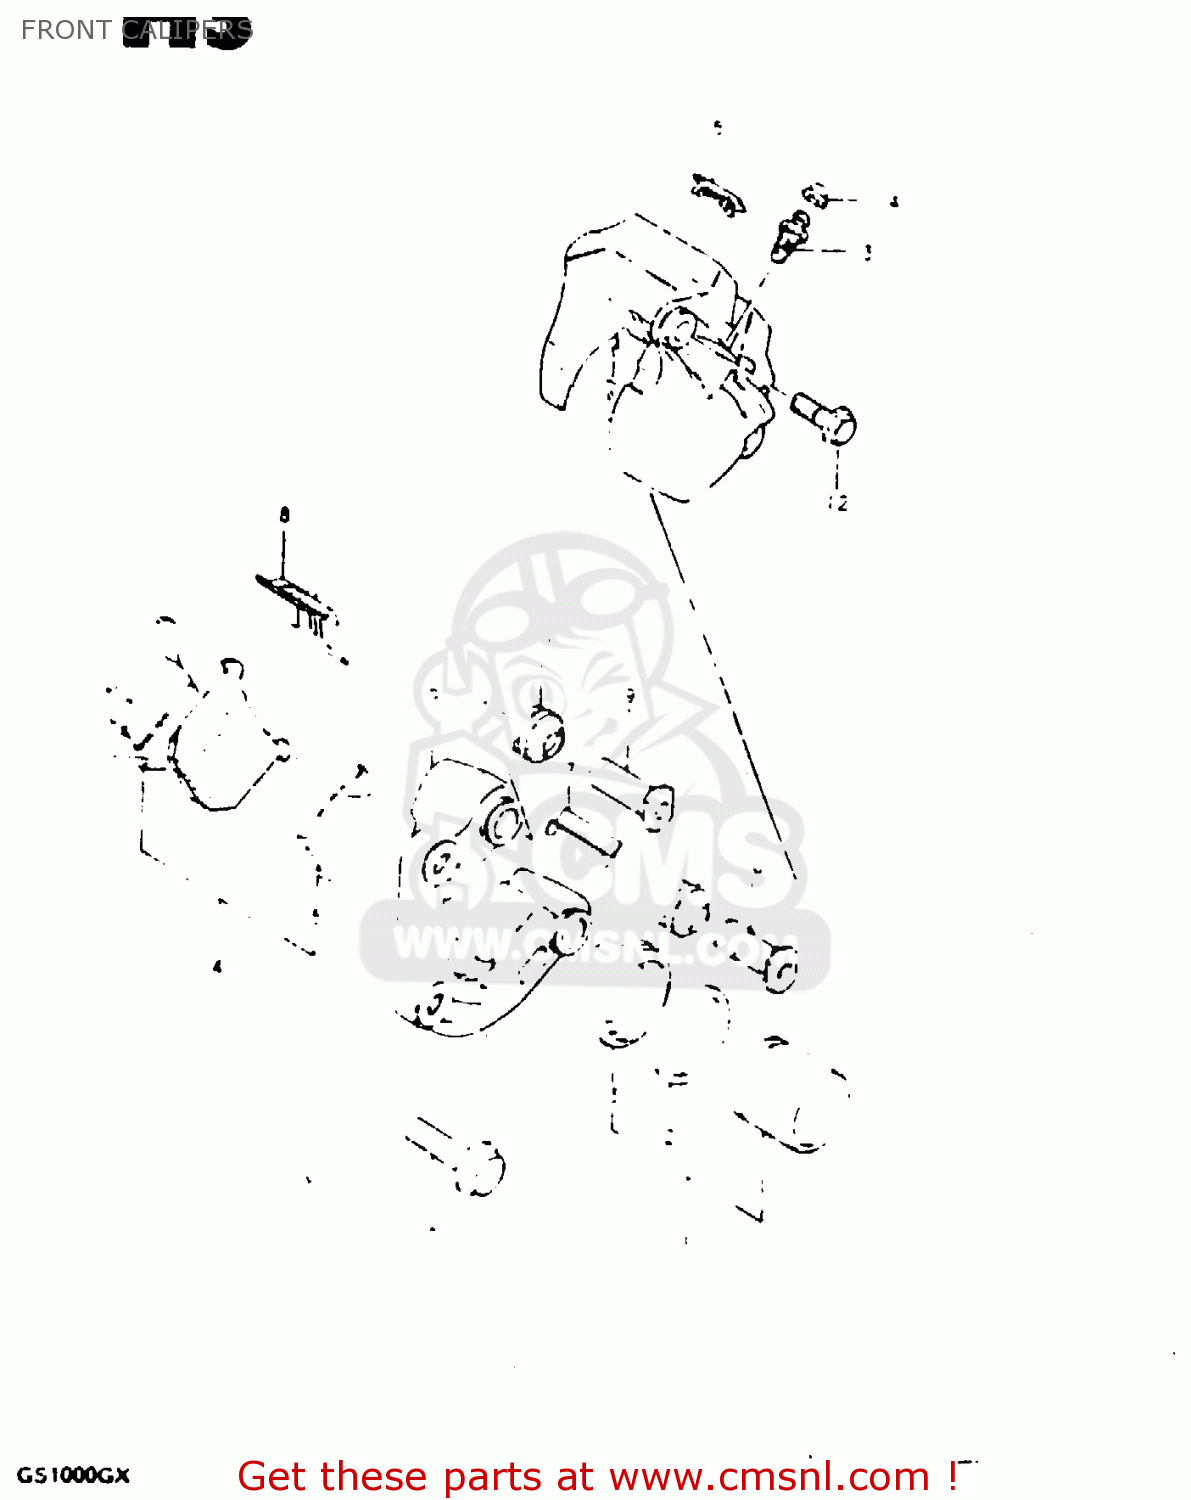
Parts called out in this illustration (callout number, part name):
1	PISTON SET
2	SEAL, PISTON
3	BOOT,PISTON
4	PAD SET (MCA)
5	SHIM,PAD
6	CARRIER,CALIPER,LEFT
7	GUIDE,PAD
8	SPRING,PAD
9	AXLE NO.1
10	AXLE NO.2
11	BOOT,AXLE
12	BOLT,CALIPER HOUSING
13	BLEEDER
14	CAP,BREATHER
15	COVER,INDICATOR
16	BOLT(10X37)
